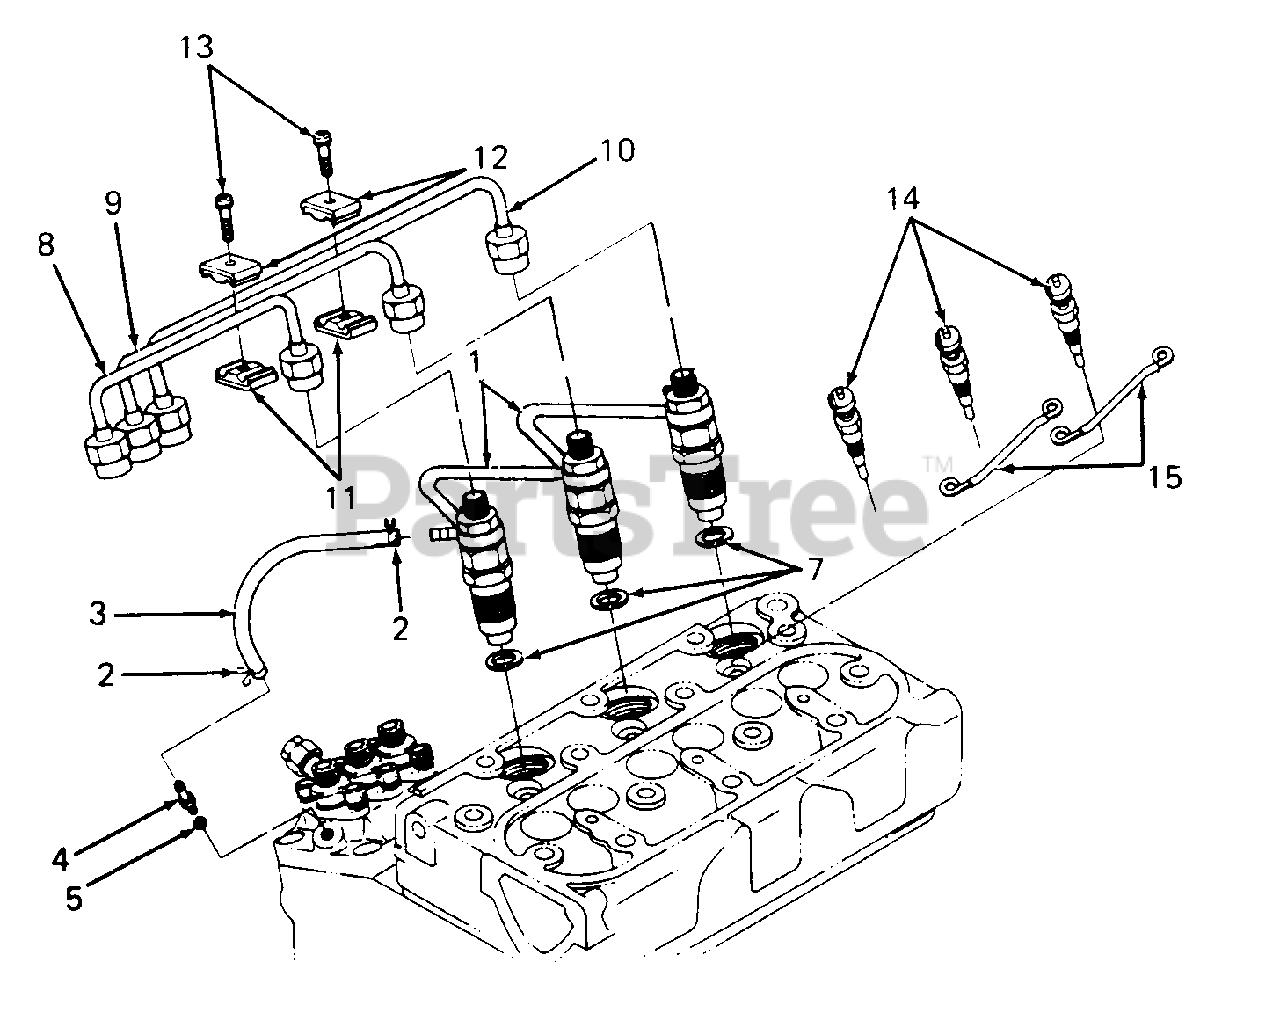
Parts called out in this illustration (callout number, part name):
1	Pipe, Overflow
3	Pipe, Overflow
7	Gasket
8	Pipe, Injection - 1
9	Pipe, Injection - 2
10	Pipe, Injection - 3
13	Screw w/Washer
14	Plug, Glow
15	Wire, Glow Plug
